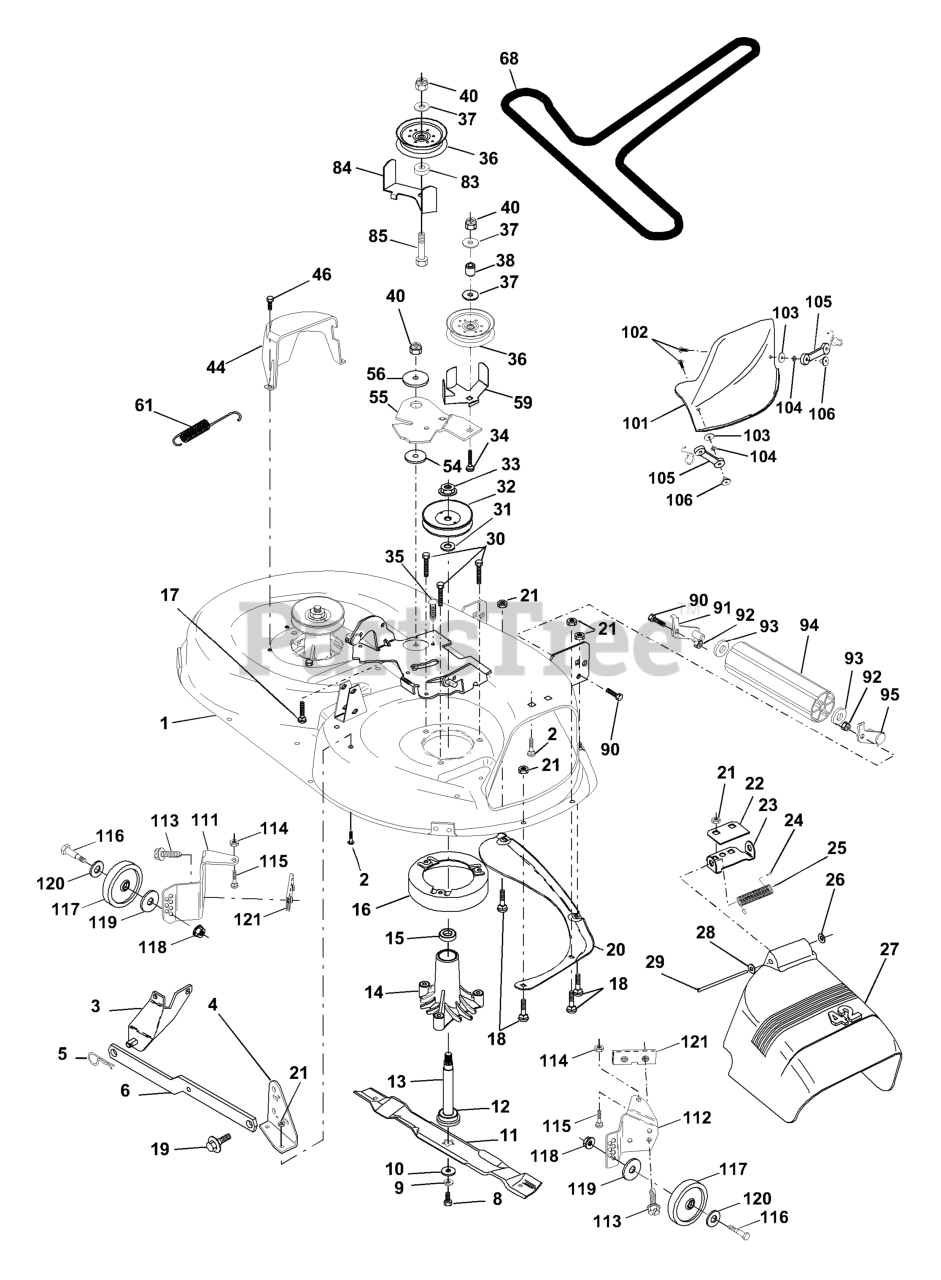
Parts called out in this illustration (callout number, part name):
1	DECK 42"
2	RP BOLT 5/16-18 X3/4 ZN/YEL GR
3	BRKT ASM SWAY BAR
4	BRKT DECK SW BAR
5	RETAINER-SPRNG RB
6	REAR SUSP ARM
8	BLADE BOLT
9	LOCKWASHER
10	WASHER.BLADE
11	BLADE.42".MULCH
12	BEARING.BALL.#6204.(MANDREL)
13	SHAFT ASM VENT
14	HOUSING.MANDREL.VENTED (MACHD)
16	STRIPPER
17	BOLT
18	BOLT
19	BOLT SHD 5/16-18
20	BAFFLE
21	LOCKNUT
22	STIFFENER BRACKET
23	DEFLECTOR BRACKET
24	CAP-SLEEVE LT
25	SPRING TORSION
26	NUT PUSH M
27	SHIELD.DEFLECTOR.MOWER.42".BLK
28	Washer 11/32 X 5/8 X 16 Ga
29	ROD.HINGE
30	SCREW
31	WASHER
32	MANDREL PULLEY
33	NUT
35	FASTENER.XMAS.TREE
36	FLAT IDLER PULLEY
37	WASHER
38	IDLER SPRING SPACER
44	GUARD MANDREL LH BLACK
46	SCREW.1/4-20X5/8
54	HARDENED WASHER
55	IDLER ARM
56	SPACER RETAINER
59	GUARD, BELT
61	SPRING EXTENSION
68	V-BELT TRIPATH
84	KEEPER BELT
85	BOLT
90	BOLT
91	BRACKET LH (A)
92	NUT
93	Washer 17/32 X 7/8 X 16 Ga
94	NOSE ROLLER
95	BRACKET RH (B)
101	COVER MULCH 42"
102	SCREW
104	LOCKWASHER #10
105	LATCH ASSEMBLY
106	WELDNUT
111	BRACKET
112	BRACKET
113	SCREW.THDROL.5/16-18X3/4.TTY
114	NUT
115	BOLT.CARR.5/16-18X1/2
116	BOLT, SHOULDER
117	WHEEL.GAUGE.BLK.4.93
118	LOCKNUT
119	WASHER.5/16.FLAT.STE.STD.
120	Washer 17/32 x 15/16 x 12 Ga.
121	BRACKET.EXTRUDED.GAGE.WHEEL
